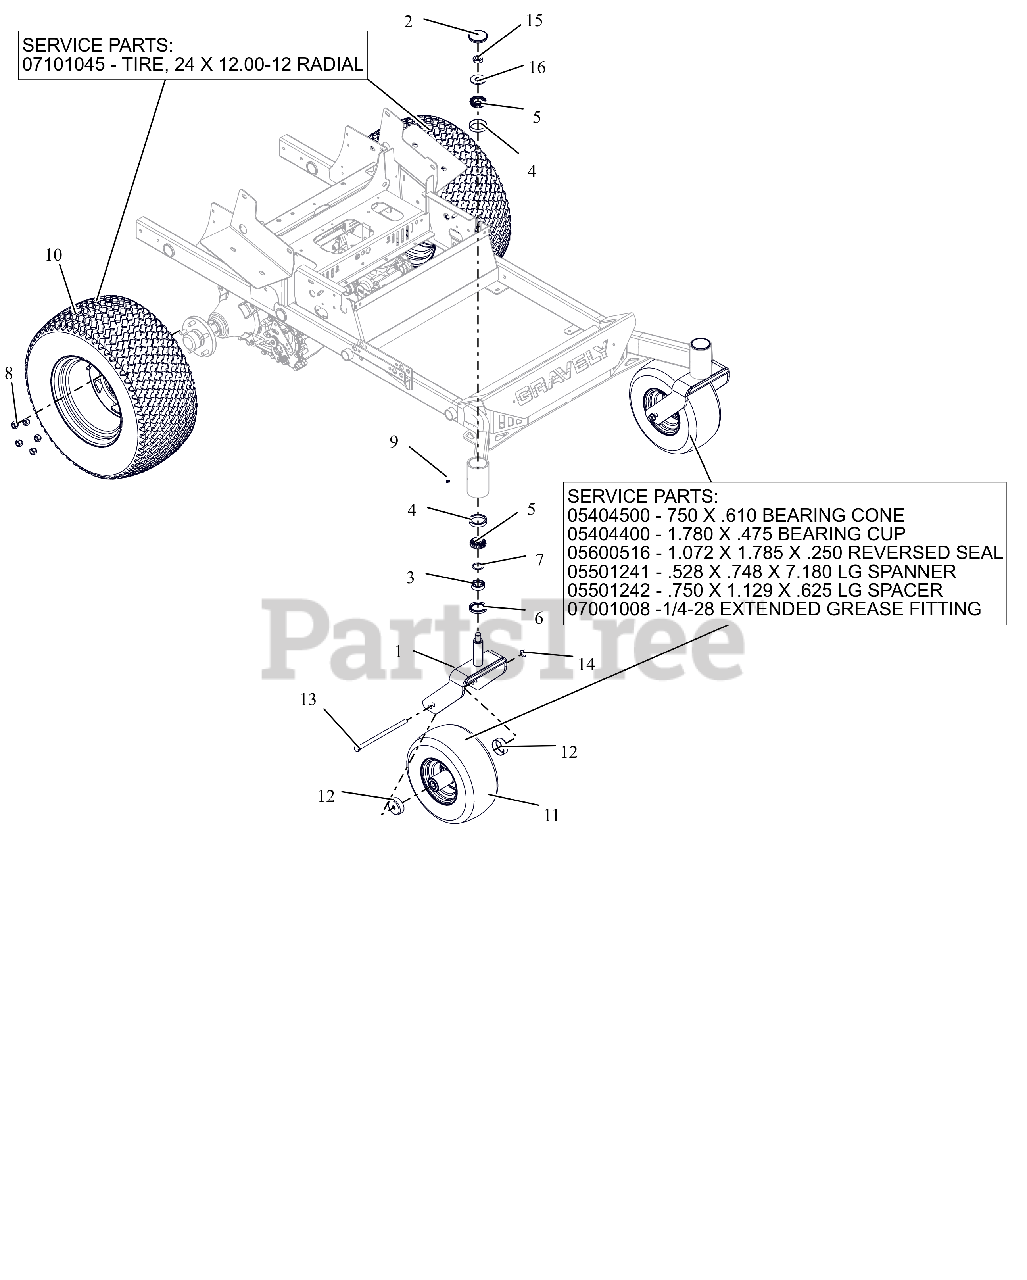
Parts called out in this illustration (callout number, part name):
1	CASTER FORK WMT - RED
2	CAP, DUST
3	SPCR, FRONT CASTER FORK
4	BRG-CUP 2.328X.465
5	BRG-CONE 1.25X.66
6	SEAL, OIL 1.75 X 2.332 X .312
8	NUT, WHEEL .50-20 ZCC
9	FTG, .25-28 FLUSH MNT GREASE
10	ASM,WHL/TIRE 24X12.00-12RADIAL
10	TIRE, 24 X 12.00-12 RADIAL
11	ASM, WHL/TIRE 15X6.00-6 SEMI
11	BRG-CONE .750X.61
11	BRG-CUP 1.781X.475
11	SEAL,1.072X1.785X.250 REVERSED
11	SPANNER, .528X.748X7.18 LG
11	SPACER, .750X1.129X.625 LG
11	GREASE FITTING 1/4-28 EXTENDED
12	SHIELD, WHEEL BEARING
13	BLT, HEX .50-13X9.00 G5 ZCC
14	NUT-LK-TOP-FLG .500-13 GF ZCC
15	NUT, JAM-TOPLOCK .750-16 ZCC
16	WSHR-FL-STL 0.812X2X0.148 ZCC
